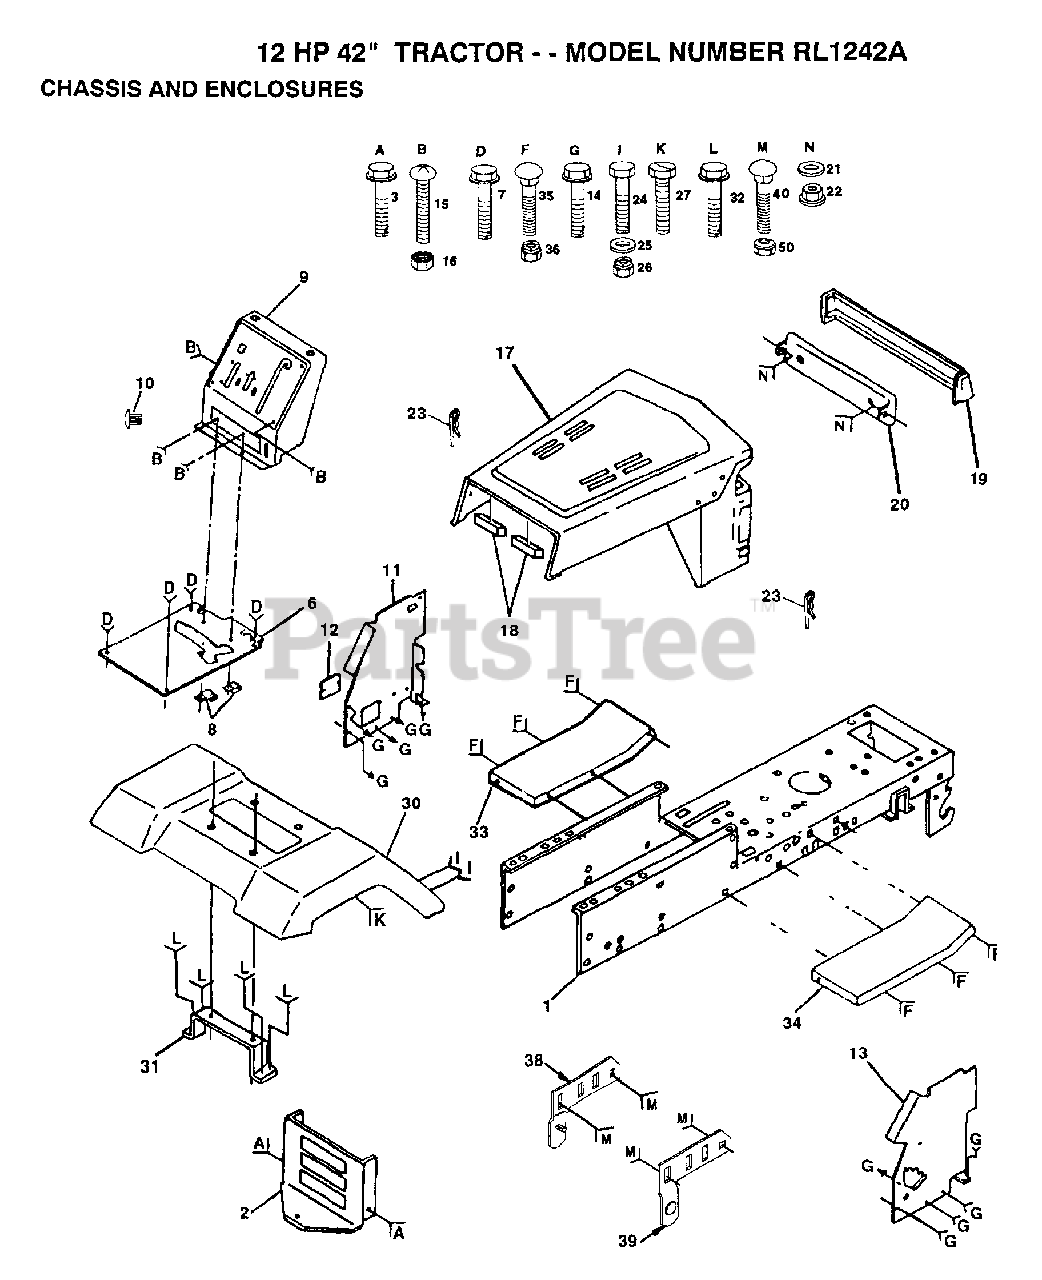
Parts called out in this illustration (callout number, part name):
3	SCREW
7	SCREW LT
8	CLIP T
10	PLUG BUTTON T
11	PANEL DASH LH
12	COVER ACCESS
14	SCREW LT
15	SCREW
17	HOOD/GRILL ASM
21	WASHER PM
22	PAL NUT LT
23	SPRING.RETAINER
25	WASHER
27	SCREW LT
32	SCREW
33	FOOTREST LH
34	FOOTREST
35	BOLT
38	PIVOT BRKT LH
39	PIVOT BRKT RH
40	BOLT
50	NUT
